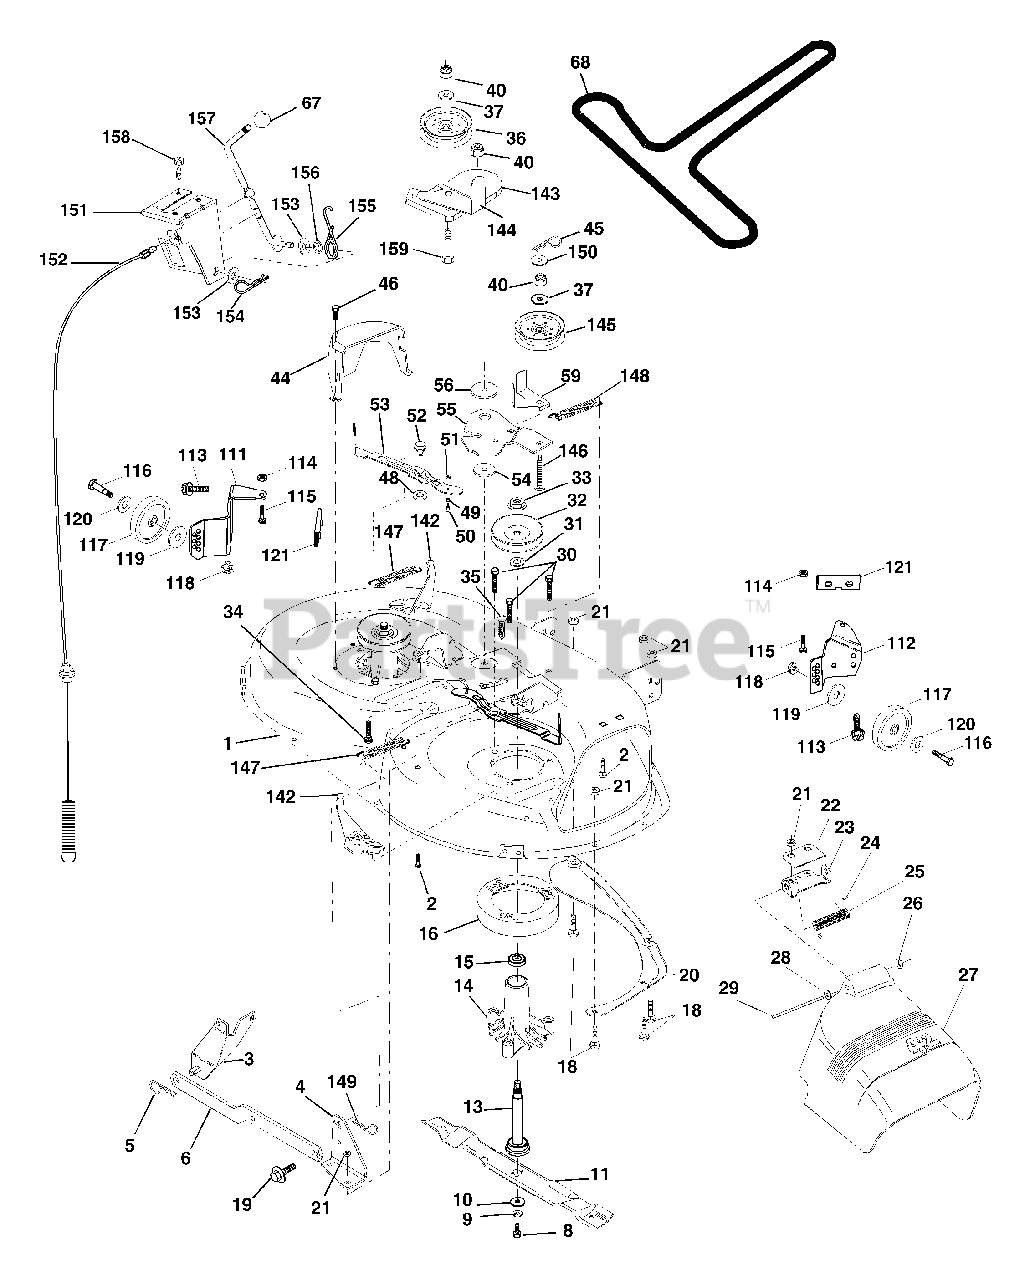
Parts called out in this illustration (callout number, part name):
1	Mower Deck Assembly, 42"
2	Bolt
3	Bracket Asm Fr. Sway Bar 3/42
4	Bracket Asm Deck 42" Sway Bar
5	Retainer Spring
6	Arm, Suspension, Rear
8	Bolt 3/8-24 x 25 Grade 8 patched
9	Washer, Lock
10	Washer, Hardened
11	Blade
13	Shaft Assembly, Mandrel, Vented
14	Housing, Mandrel, Vented
15	Bearing, Ball, Mandrel
16	Stripper, Vented Mower Deck
18	Bolt, Carriage 5/16-18 x 5/8
19	Bolt, Shoulder
20	Baffle, Vortex
21	Nut
22	Stiffener Bracket
23	Bracket, Deflector Mower 42"
24	Cap, Sleeve 80 x 112 Blk Mower
25	Spring, Torsion, Deflector 2 52
26	Nut, Push Phos & Oil
27	Shield, Deflector 42" Blk
28	Washer 11/32 x 5/8 x 16 Gauge
29	Rod, Hinge 42" 6 75 W/G
30	Screw Thdrol Washer Head
31	Washer, Spacer Mower Vented
32	Pulley, Mandrel
33	Nut, Toplock 9/16
34	Bolt
35	Fastener, Christmas Tree
36	Pulley, Idler, Flat
37	Washer 13/32 x 13/16 x 16 Gauge
40	Nut
44	Guard, Mandrel, LH
45	Retainer
46	Screw, Thdrol 1/4-20 x 5/8 T
48	Washer, Hardened
49	Roller Assembly, Cam Follower
50	Bolt, Shoulder #10-24 Grade 5
51	Locknut
52	Bolt, Shoulder 5/16-18 UNC
53	Arm Assembly, Pad, Brake
54	Washer, Hardened
55	Arm, Idler
56	Spacer, Retainer
59	Guard TUV Idler
67	Knob
68	V-Belt, 42" Mower
111	Bracket, Gauge, Wheel LH
112	Bracket, Gauge, Wheel RH
113	Screw Tapping 5/16 - 18 Unc
114	Nut, Keps 5/16 - 18 UNC
115	Bolt, Carriage 5/16-18 x 1/2
116	Bolt, Shoulder
117	Wheel, Gauge
118	Nut Centerlock 3/8-16
119	Washer 3/8 x 7/8 x 14 Ga.
120	Washer 17/32 x 15/16 x 12 Ga.
121	Bracket, Extruded
142	Arm Spring Brake Mower
143	Bracket Arm Idler 42"
144	Keeper Belt 42" Clutch Cable
145	Pulley Idler Flat
146	Bolt Carriage Idler
147	Spring Extension
148	Spring Return Idler
149	Retainer Spring Yellow
150	Washer 9/32 x 3/4 x 16 Ga.
151	Bracket Clutch Cable
152	Clutch Cable 42"
153	Washer Flat 3/8" Type B
154	Spring Retainer
155	Spring Retention LVR CLTCH CAB
156	Spacer Clutch Cable
157	Rod Clutch Cable 3/8"
158	Screw Hex Thd Cut 1/4-20 x 5/8
159	Bolt Rdhd Sqn 3/8-16 UNC x 1-3/4
